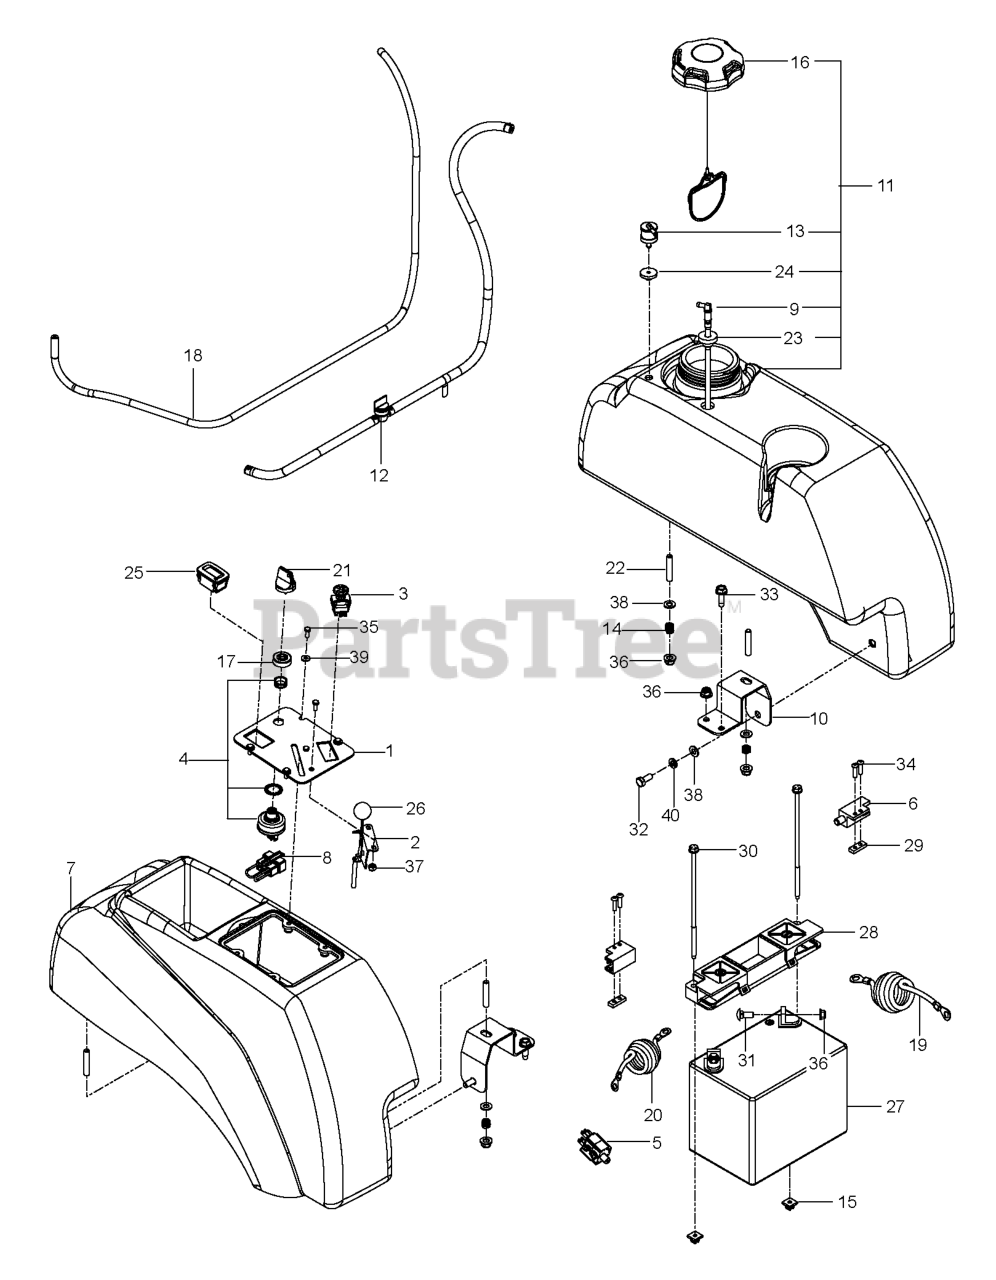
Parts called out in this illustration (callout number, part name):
1	PLATE.CONSOLE.BLACK
2	THROTTLE CONTROL W/BALL KNOB
3	RP SWITCH.PTO.TERMINAL.STD.RED
4	SWITCH, IGNITION, INDAK
5	SWITCH, BRAKE 3P
6	SWITCH INTERLOCKT
7	FENDER CONSOLE
8	PLUG, TIMER
9	FITTING, FUEL
10	SUPPORT, TANK, BLK
11	FUEL.TANK.ASSY.LH.MZ.GRY
12	FUEL LINE ASM
13	VALVE.FUEL.CHECK
15	PUSH NUT-NYLON
16	CAP, FUEL
17	CAP IGNITION NUT
18	HOSE, VAPOR 3/16 X 48"
19	POST.CABLE LONG
20	NEG. CABLE, 28"
21	KEY, IGNITION
22	STUD, 5/16C
23	RUBBER GROMMET
24	GROMMET, CHECK VALVE
25	GUAGE.SRVCMNDR.HRMTR.
26	KNOB.ROUND.BALL.BLACK
27	BATTERY, 12 V 330 AMP
28	BATTERY HOLD DOWN
29	TAPPED PLATE
30	BOLT - 1/4-20 X 7.5
31	BOLT 5/16C X 3/4" CARRIAGE
32	HCS 5/16C X 3/4
33	RP BLT 5/16-18 X 1 THRD FORM D
34	5/16-18 NYLOC FLANGE NUT
35	HCS #10-24 X 1/2
36	SCR #10-24 X .75 SKT HD BLK
37	NUT 10-24 NYLOC
38	FLAT WASHER 5/16 SAE
39	WASHER #10
40	WASHER.LOCK.HVY.HLCL.SPR.5/16
